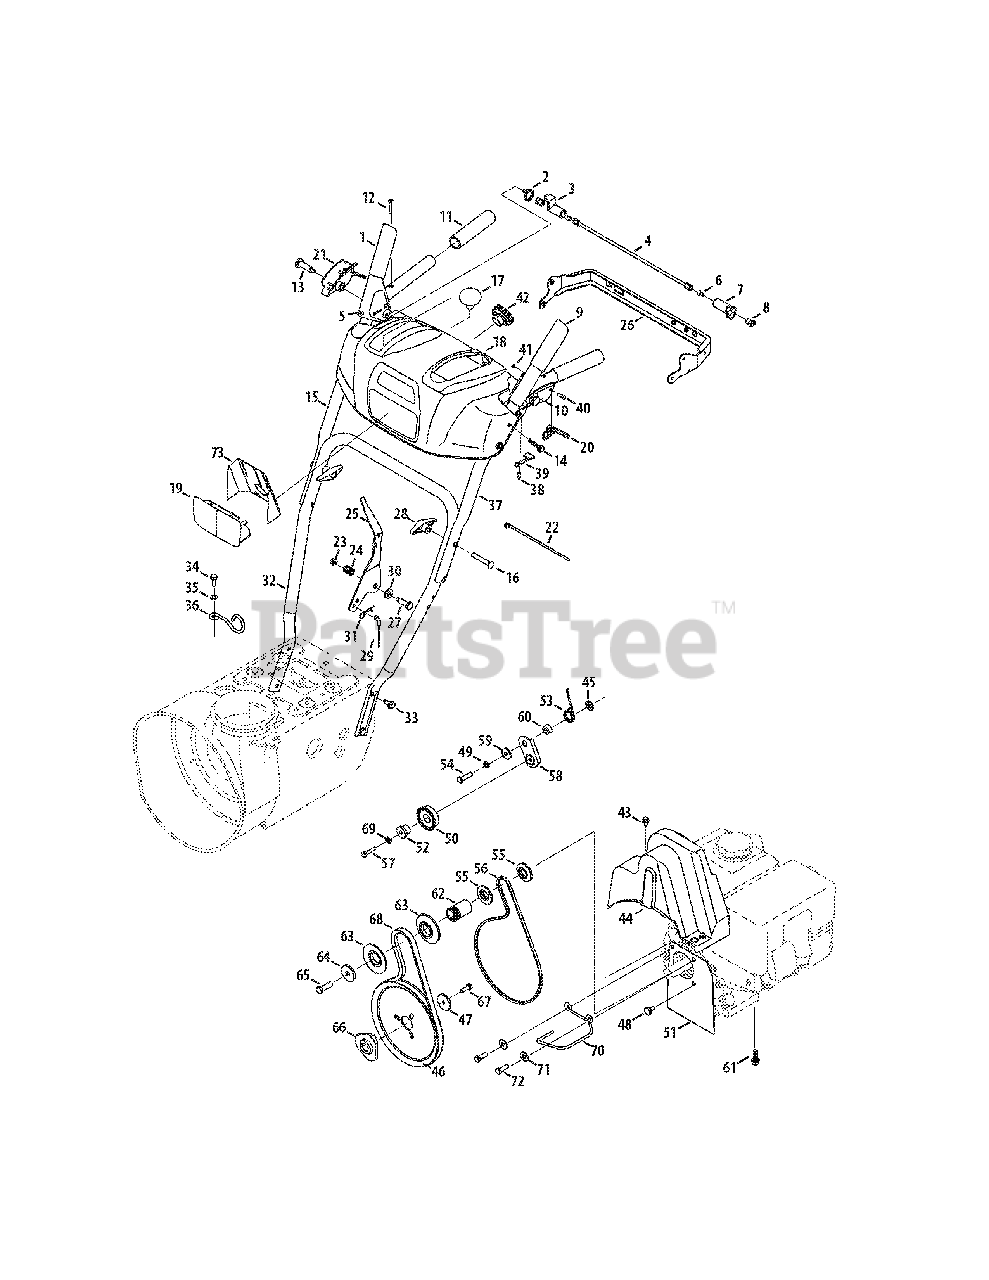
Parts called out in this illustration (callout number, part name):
1	Handle Engagement Ass’y RH
2	Torsion Spring
3	Lock Plate
4	Pivot Rod
5	Rubber Bumper
6	Screw, 1/4-20 x .500
7	Clutch Lock Cam
8	Shoulder Nut, 1/4-20
9	Handle Engagement Assembly LH
10	Handle Clutch Lock LH Assembly
11	Handle Grip
12	Screw, #10-24 x 0.375
13	Shoulder Screw, 1/4-20
14	Screw, 1/4-20 x 1.625
15	Upper Handle RH
16	Carriage Screw, 5/16-18 x 2.25
17	Shift Knob
18	Handle Panel, includes Ref. 19 & 73
20	Trigger
21	Handle Clutch Lock RH Assembly
22	Cable Tie
23	Flange Lock Nut, 1/4-20
24	Compression Spring
25	Shift Lever
26	Panel Bracket
27	Shoulder Screw
28	Wing Knob
29	Speed Selector Cable
30	Flat Washer
31	Click Pin
32	Lower Handle
33	Screw, 5/16-18 x 0.75
34	Screw, M8-1.25
35	Flat Washer, .330 x .630 x .0635
36	Cable Control Wire
37	Upper Handle LH
38	Screw, #8-16 x 0.50
39	Clutch Lock Spring
40	Pin, 3/16
41	Retainer Ring
42	Headlight Socket
43	AB Screw, 1/4-20 x 0.625
44	Belt Cover
45	Push-on Nut
46	Auger Pulley
47	Flat Washer
48	Shoulder Screw
49	Lock Washer
50	Idler Pulley Assembly
51	Plt., Cvr.
52	Spacer
53	Torsion Spring
54	Hex Screw, 5/16-24 x 1.25
55	Pulley Half
56	Belt, Wheel Drive
57	TT Screw, 1/4-20 x 1.25
58	Drive Clutch Idler Bracket
59	Shoulder Spacer
61	TT Sems Screw, 3/8-16 x 1.0
62	Spacer
63	Pulley Half
64	Flat Washer
65	Hex Bolt, 3/8-24 x 1.25
66	Pulley Adapter
67	Hex Bolt, 5/16-24 x 0.875
68	V-Belt,.500 x 35.00 Lg
69	Lock Washer
70	Belt Guide
71	Flat Washer, .349 x .879 x .063
72	Screw, 5/16-24 x 1.00
73	Lens Label
